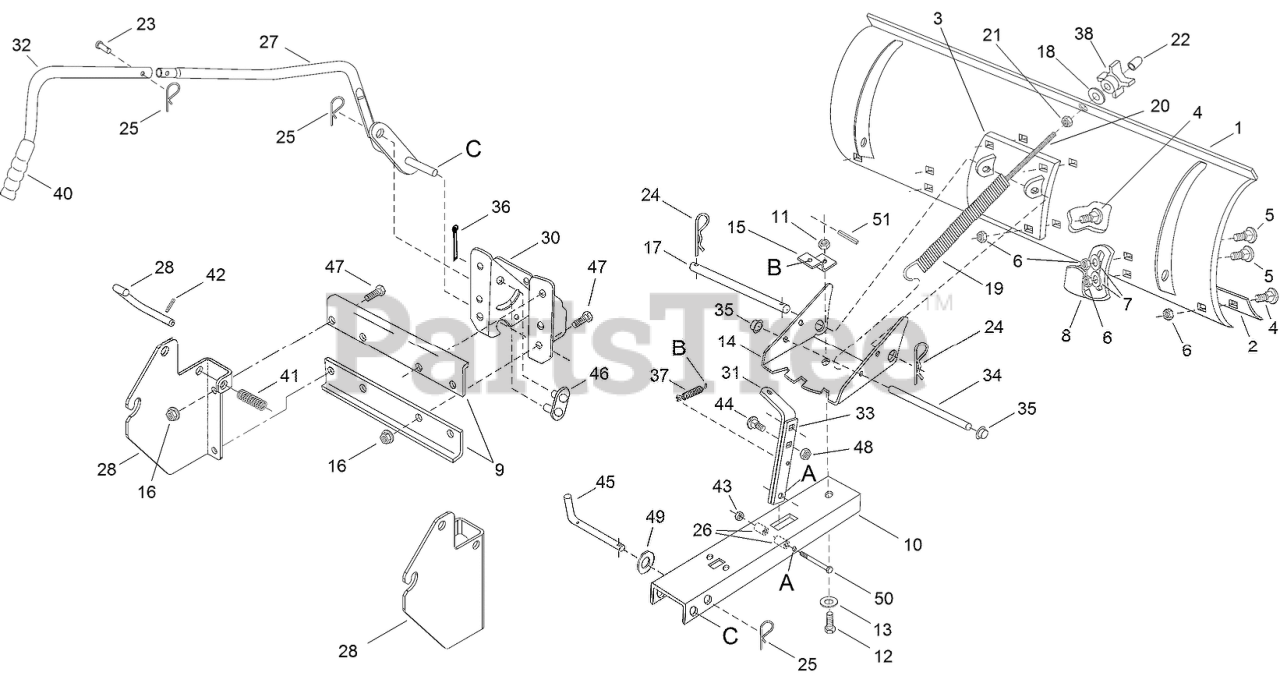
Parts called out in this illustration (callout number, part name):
2	PLATE-WEAR
3	REINFORCEMENT PLATE ASM
6	NUT-NYLOCK
7	WASHER
8	SKID-SHOE
9	BRACKET-SUPPORT, ANGLE
10	CHANNEL-PUSH
11	NUT-LOCK
12	BOLT-PIVOT, SPECIAL
13	WASHER-FLAT
14	PLATE-PIVOT
15	BRACKET-MOUNTING, SPRING
16	NUT-LOCK, FLANGED
17	SHAFT-PIVOT
18	WASHER-FLAT
19	SPRING-BLADE ADJUST
20	BOLT-HEX
21	NUT-HEX
22	CAP-PLASTIC
23	PIN-CLEVIS, LIFT HANDLE
24	PIN-HAIR
25	PIN-QUICK ATTACH
26	SPACER
27	LOWER LIFT HANDLE ASM
28	KIT-BRACKET, FAST ATTACH
30	BRACKET-SUPPORT, PIVOT
31	BAR-LOCK, ANGLE (LONG)
32	HANDLE-LIFT, UPPER
33	BAR-LOCK, ANGLE (SHORT)
34	ROD-MOUNT, SPRING
35	NUT-PUSH
36	PIN-COTTER
37	SPRING-LOCK, ANGLE
40	GRIP-HANDLE
41	SPRING-COMPRESSION
42	PIN-SPRING
43	NUT-LOCK
44	BOLT-CARR
45	SHAFT-CHANNEL, PIVOT
46	LINK-LIFT
47	BOLT-HEX
48	NUT-LOCK, HEX
49	WASHER
50	BOLT-HEX
51	PIN-SPRING
